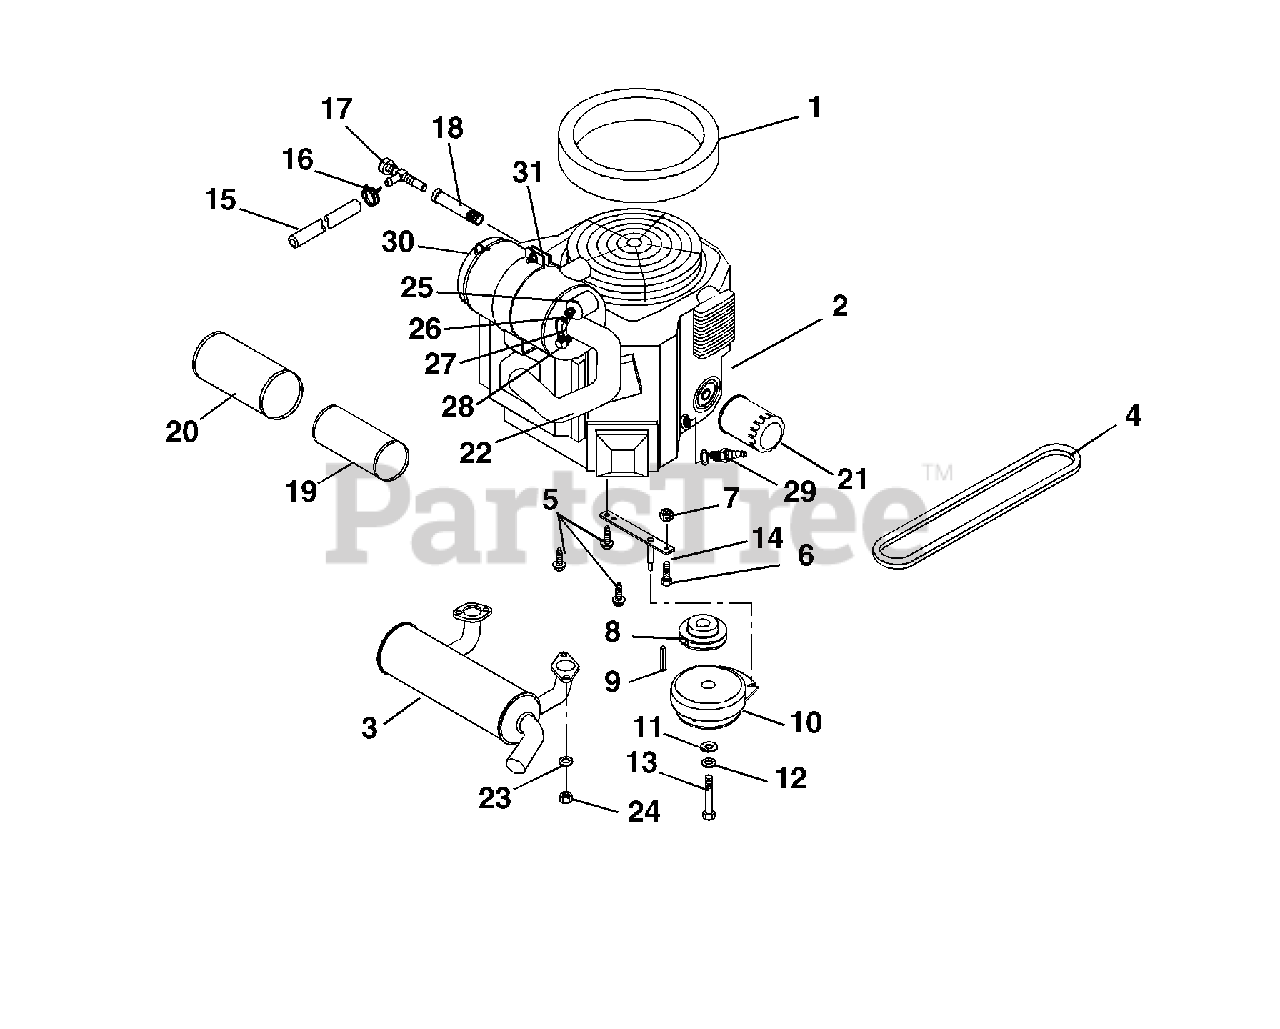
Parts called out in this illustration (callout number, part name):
1	Seal-Foam
2	Engine, Kohler EFI26
3	Muffler, Kohler EFI
4	V-Belt, A-Section 28.29 x .531
5	Screw-Tapping Hex-Washer-Head .38-16 x 1.00
6	Bolt-Hex .31-18 x 1.75 Grade 5
7	Nut-Locking-Center .31-18
8	Pulley-4.46 DIA x 1.12 Bore
9	Key-Square .25 x 1.00 x .25
10	Electric Clutch
11	Washer-Flat-Steel .515 x 1.625 x .250
12	Washer-Locking .44 x .109
13	Bolt-Hex .44-20 x 3.00 Grade 5
14	Anchor-Clutch
15	Gas Line-Bulk 1/4" ID
16	Hose-Clamp
17	Cock-Oil Drain
18	Adapter-Oil Drain
19	Element, Inner Safety
20	Element, Outer Primary
21	Oil Filter
22	Hose, Air Intake
23	Washer-Lock .31 x .078 Regular
24	Nut-Hex M8-1.25
25	Filter Minder
26	Nipple, .125" NPT
27	Elbow, 45 Degree 1/8" NPT
28	Elbow,Adapter 90 Degree, Brass, .125 x .125
29	Spark Plug
30	Assembly, Air Cleaner
31	Bracket, Air Cleaner Mount
